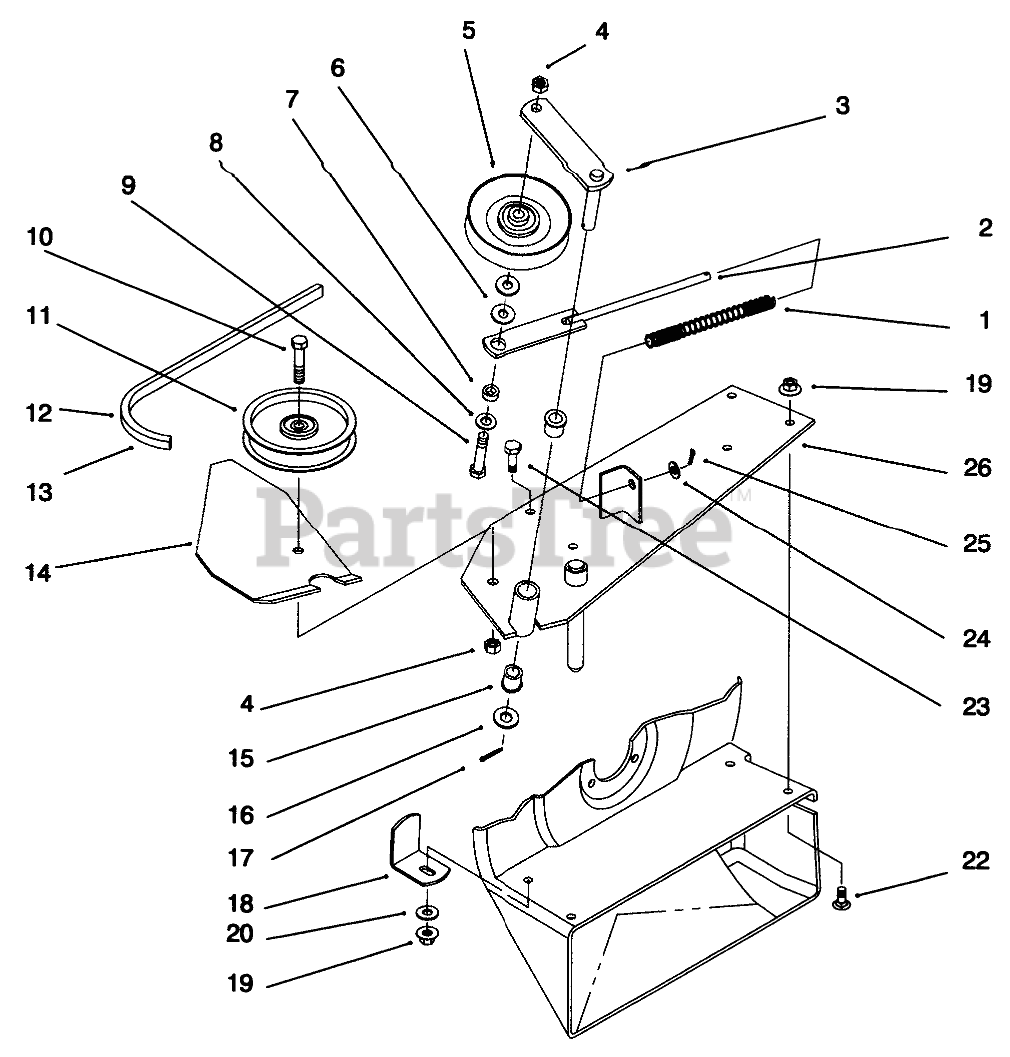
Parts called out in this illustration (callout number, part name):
1	SPRING-COMPRESSION
2	SPRING-ROD
3	IDLER ARM ASM
4	NUT-LOCK, NI
5	PULLEY-IDLER
6	WASHER-FLAT
7	SPACER
8	WASHER-FLAT
9	SCREW-HH
10	SCREW-HH
11	PULLEY-IDLER
12	V-BELT
13	V-BELT
14	SHIELD SUPPORT B
15	BUSHING
16	WASHER-FLAT
17	PIN-COTTER
18	BRACKET-SUPPORT, HOUSING
19	NUT-HF
20	WASHER-FLAT
22	BOLT-CARR
23	SCREW-HH
24	WASHER-PLAIN
25	PIN-COTTER
26	BLOWER-MTG ASM
